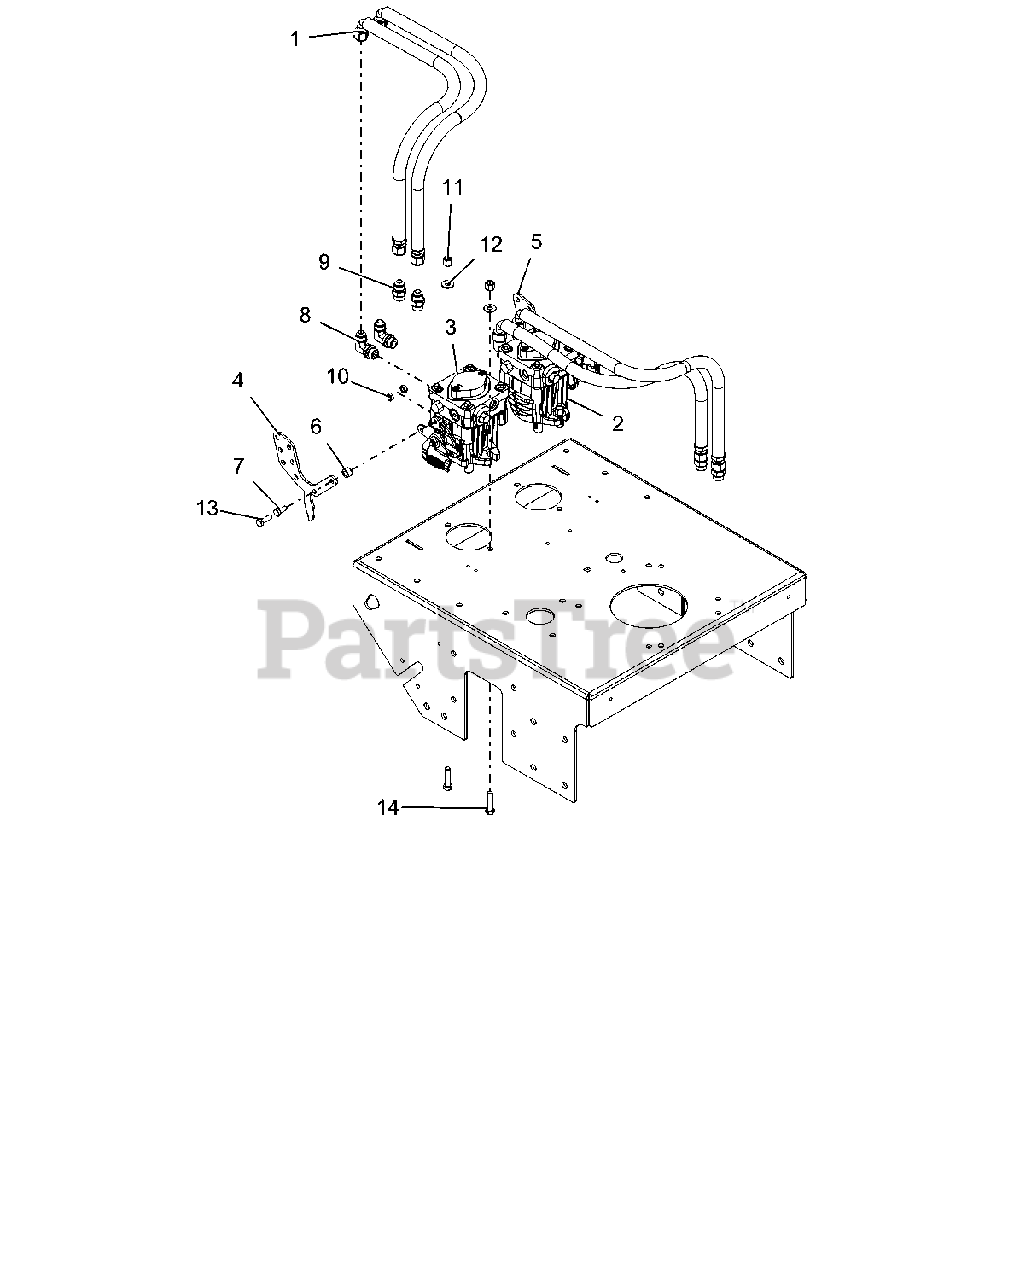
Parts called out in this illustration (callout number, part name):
1	HOSE, HYD 1/2 X 26 1/2 EZFLEX
2	PUMP, LH HYD PE (10CC)
3	PUMP, RH HYD PE (10CC)
4	BRKT, RH PUMP CONTROL WRS
5	BRKT, LH PUMP CONTROL WRS
6	BSHG, SLV REV
7	BLT-HEX .31-18X.75 GR5 YWZC
8	FTG, ADP JIC-ORB 6801-08-08
9	FITTING, STRAIGHT
10	NUT-LK-CTR-JAM .31-18 YWZC
11	NUT-LK-NYL .38-16 YWZC
12	WSHR-FL-STL.38X.875X.083 YWZC
13	BLT-HEX .31-18X1.00 GR5 YWZC
14	BLT-HEX .38-16X1.50 GR5 YWZC
